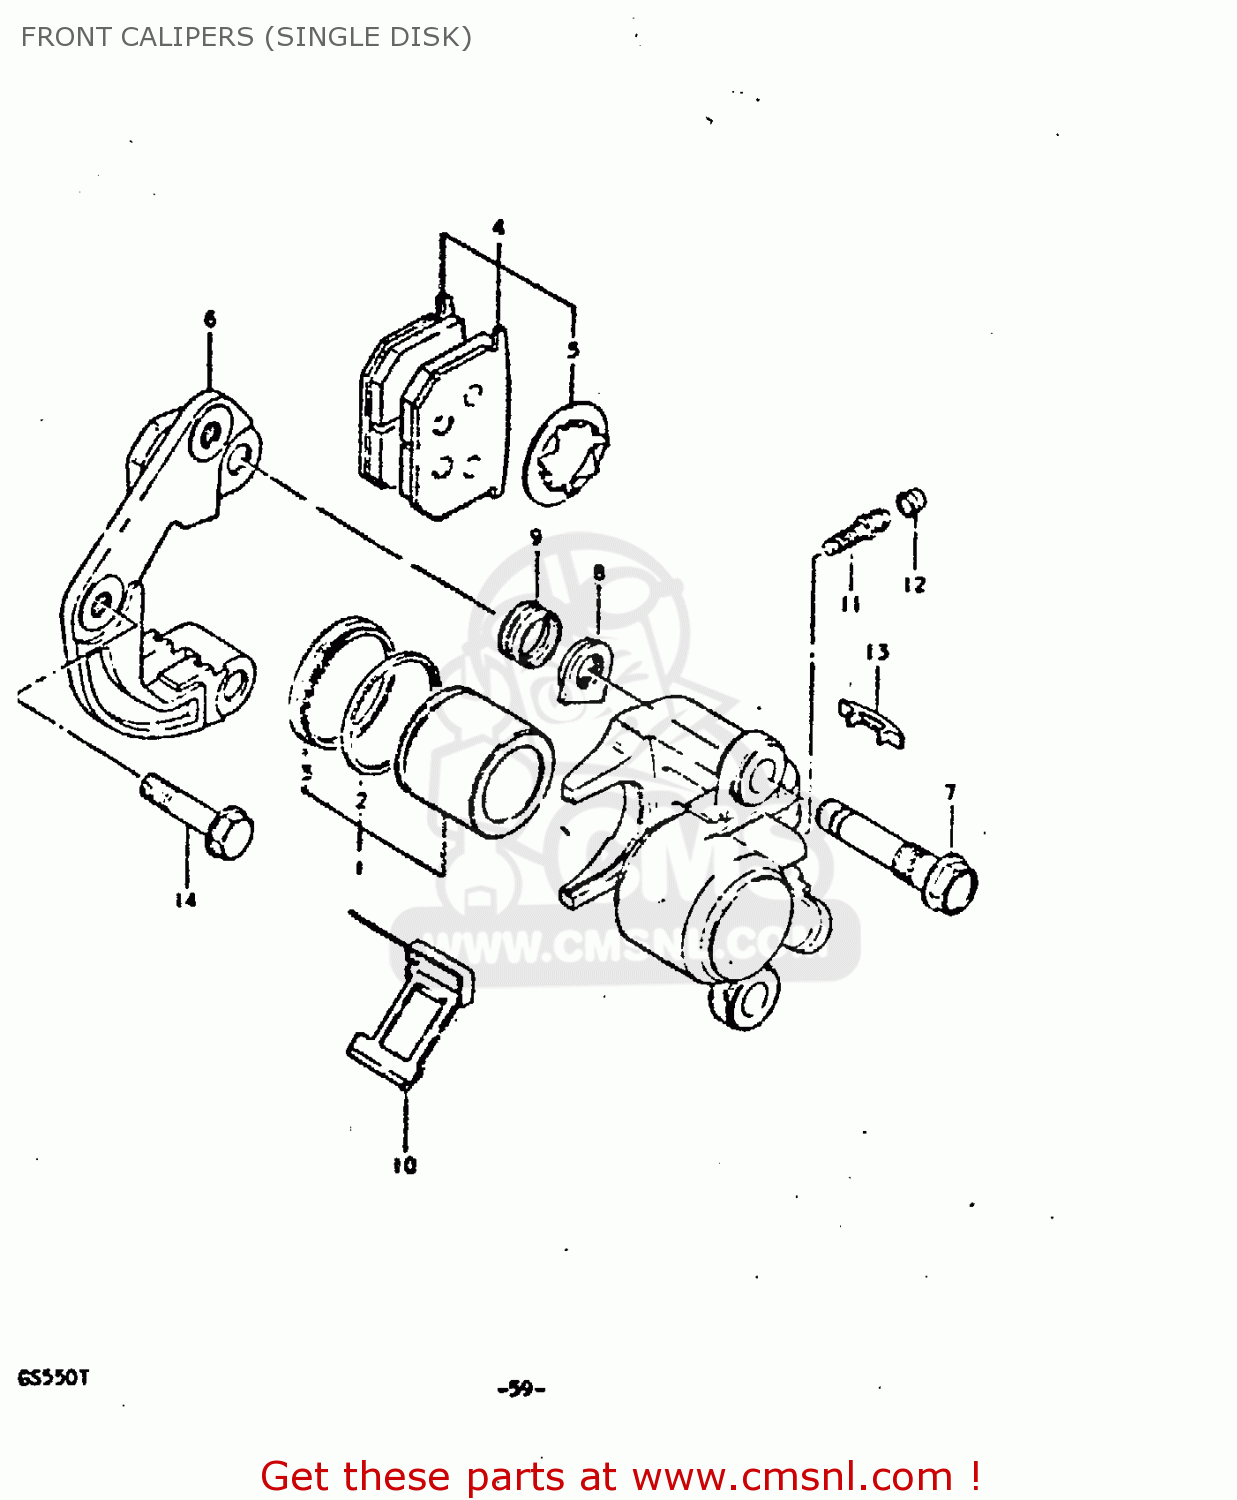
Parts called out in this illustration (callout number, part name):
1	PISTON SET
2	SEAL,PISTON
3	BOOT,PISTON
4	PAD & SHIM SET (MCA)
5	SHIM,PAD
6	BRACKET
7	AXLE,CALIPER
8	NUT,CALIPER AXLE
9	BOOT
10	SPRING
11	BREATHER
12	CAP,BLEEDER PL
13	COVER,INDICATOR
14	BOLT(10X37)
